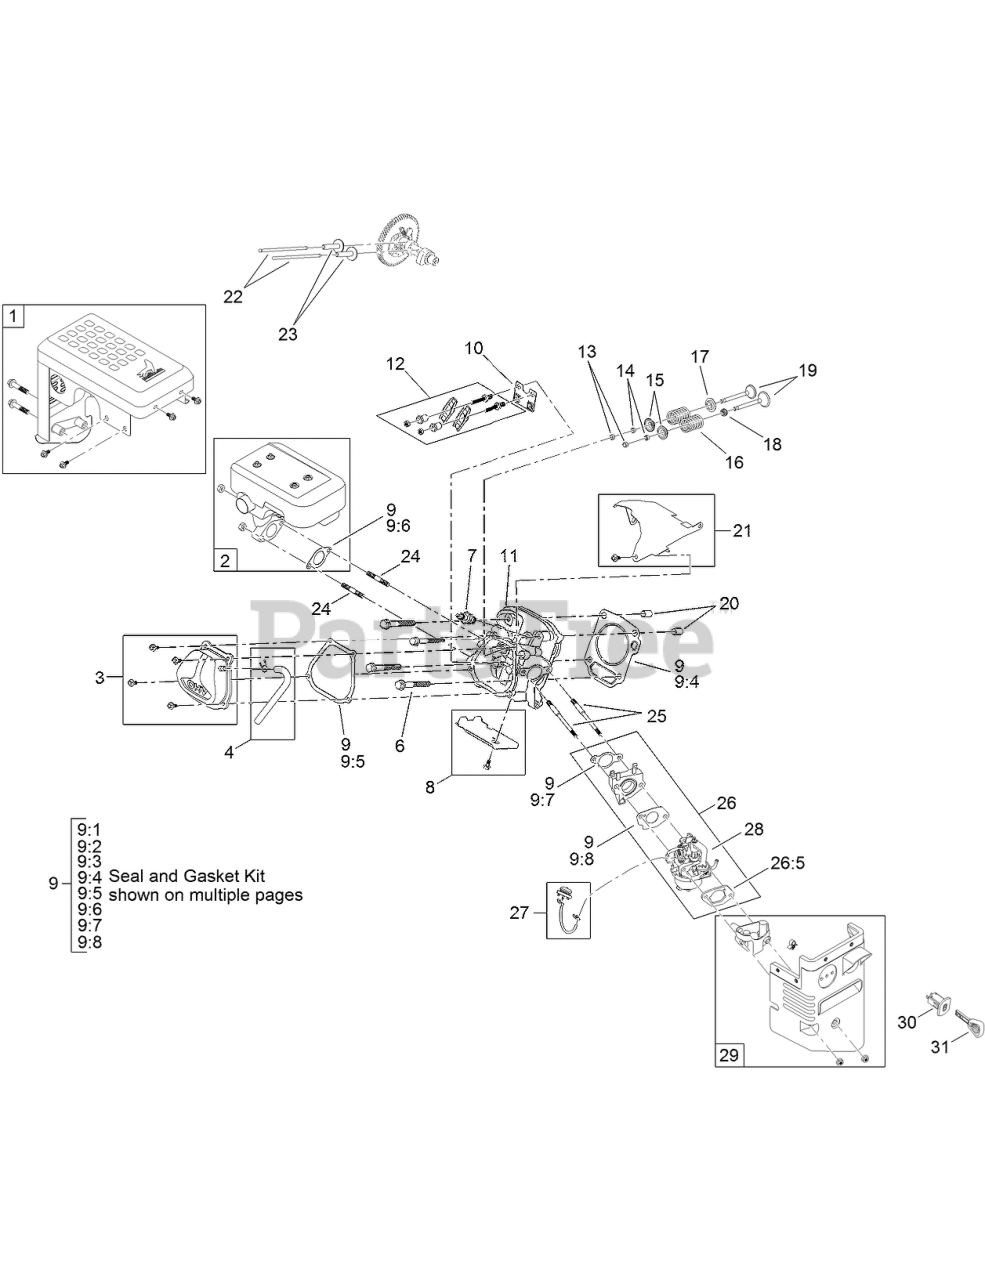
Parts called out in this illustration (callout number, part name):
1	MUFFLER SHIELD KIT
2	MUFFLER KIT
3	VALVE COVER KIT
4	BREATHER TUBE KIT
6	SCREW-HHF
7	PLUG-SPARK
8	LOWER HEAT SHROUD KIT
9	SEAL AND GASKET KIT
9:1	Seal-Oil
9:2	Seal-Oil
9:3	GASKET-COVER, CRANKCASE
9:4	GASKET-HEAD, CYLINDER
9:5	GASKET-COVER, VALVE
9:6	Gasket-Exhaust
9:7	GASKET-CARBURETOR
9:8	GASKET-CARBURETOR
10	PLATE-GUIDE, PUSH ROD
11	HEAD-CYLINDER
12	ROCKER ARM ASM
13	ROTATOR-VALVE
14	KEEPER-VALVE
15	RETAINER-SPRING, VALVE
16	SPRING-VALVE
17	SEAT-SPRING, VALVE
18	SEAL-STEM, VALVE
19	VALVE KIT
20	PIN-DOWEL
21	UPPER HEAT SHROUD KIT
22	ROD-PUSH
23	LIFTER-VALVE
24	STUD-MOUNT, MUFFLER
25	STUD-MOUNT, CARBURETOR
26	COMPLETE CARB SERVICE KIT
26:5	GASKET-COATED, RUBBER
27	PRIMER KIT
28	CARB REPAIR KIT WITH GASKETS
29	HEATER BOX KIT
30	SWITCH-KEY
